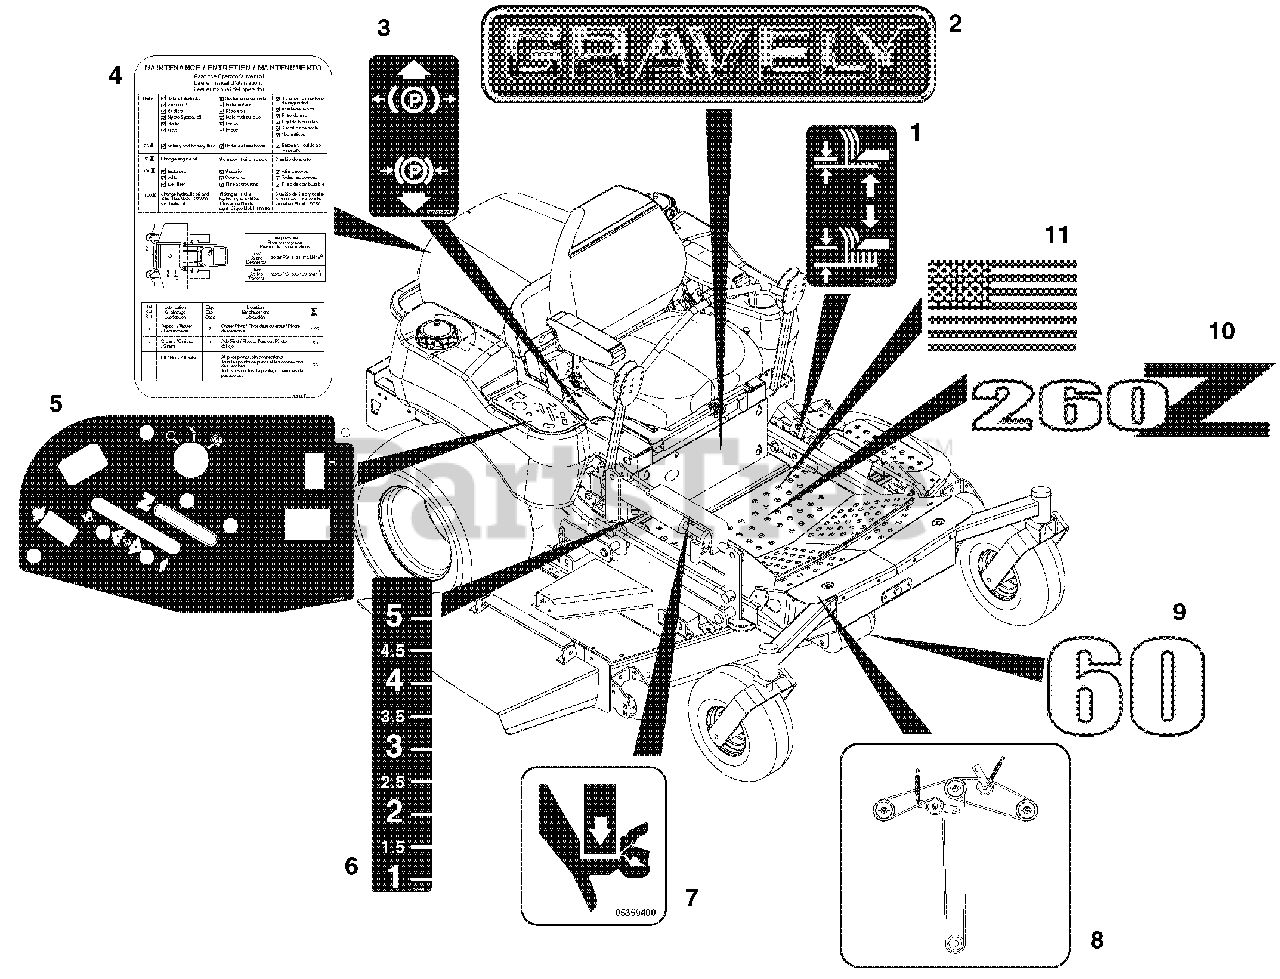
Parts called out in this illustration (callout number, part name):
1	Decal, Lift Lever
2	Decal, 15 in. Gravely Logo
3	Decal, Parking Brake Lever
4	Decal, Service Instructions
5	Decal, Control Panel (045, 046, 047, 049, 052, 053)
6	Decal, Height of Cut
7	Decal, Pinch Point
8	Decal, Belt Diagram (045, 046, 047, 048, 052, 053)
9	Decal, 60 (046, 047, 048, 053)
10	Decal, PM-260Z (046, 047, 048, 053)
11	Decal, American Flag
